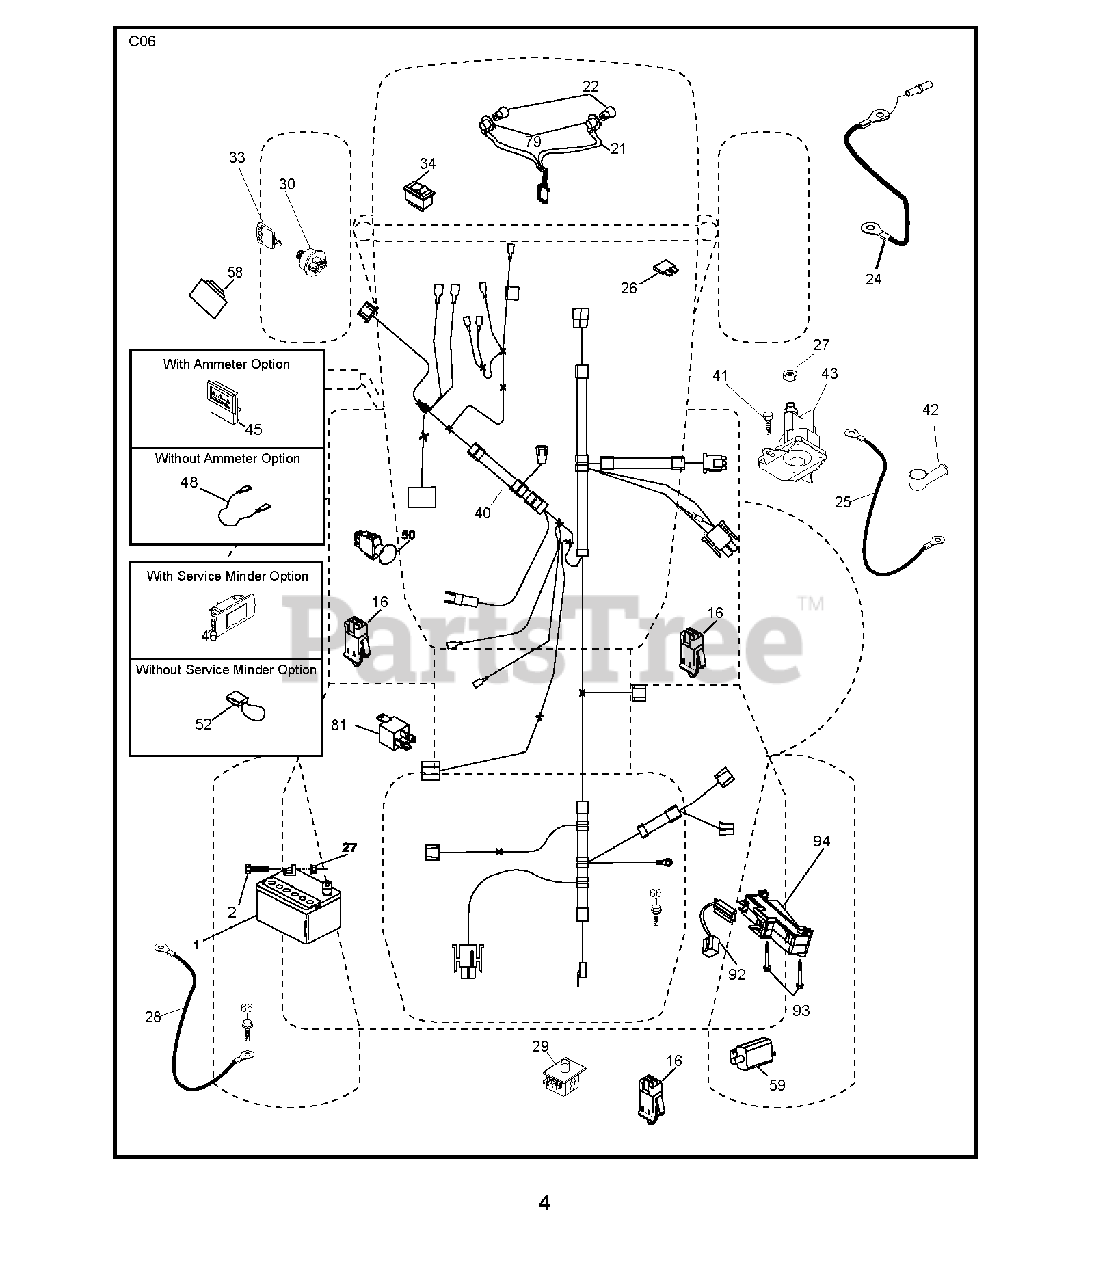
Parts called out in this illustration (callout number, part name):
1	REPL BY 532 12 38-99
16	SWITCH INTERLOOK PUSH-IN
21	HARNESS.W/LIGHT SOCKET
22	LIGHTBULB
24	CABLE BATTERY 6 GA. 11" RED
25	CABLE BATTERY
26	FUSE 20AMP
27	NUT
28	CABLE GROUND
29	SWITCH.SEAT.DP W/RAMPS
30	SWITCH.IGN.DELTA.W.LGH.ROS
33	KEY.CHAIN.BLISTER.PACK.GEN.INT
34	SWITCH LT
42	TERMINAL COVER
43	SOLENOID.W/BRASS.PLUNG
46	GUAGE.SRVCMNDR.HRMTR.
50	PTO SWITCH
58	BUZZER
79	BULB HOLDER ASM.
81	RELAY.ASSY.T
92	HARNESS.PIGTAIL.CONSLE
93	SCREW.PLASTITE
94	MODULE.REVERSE.ROS
